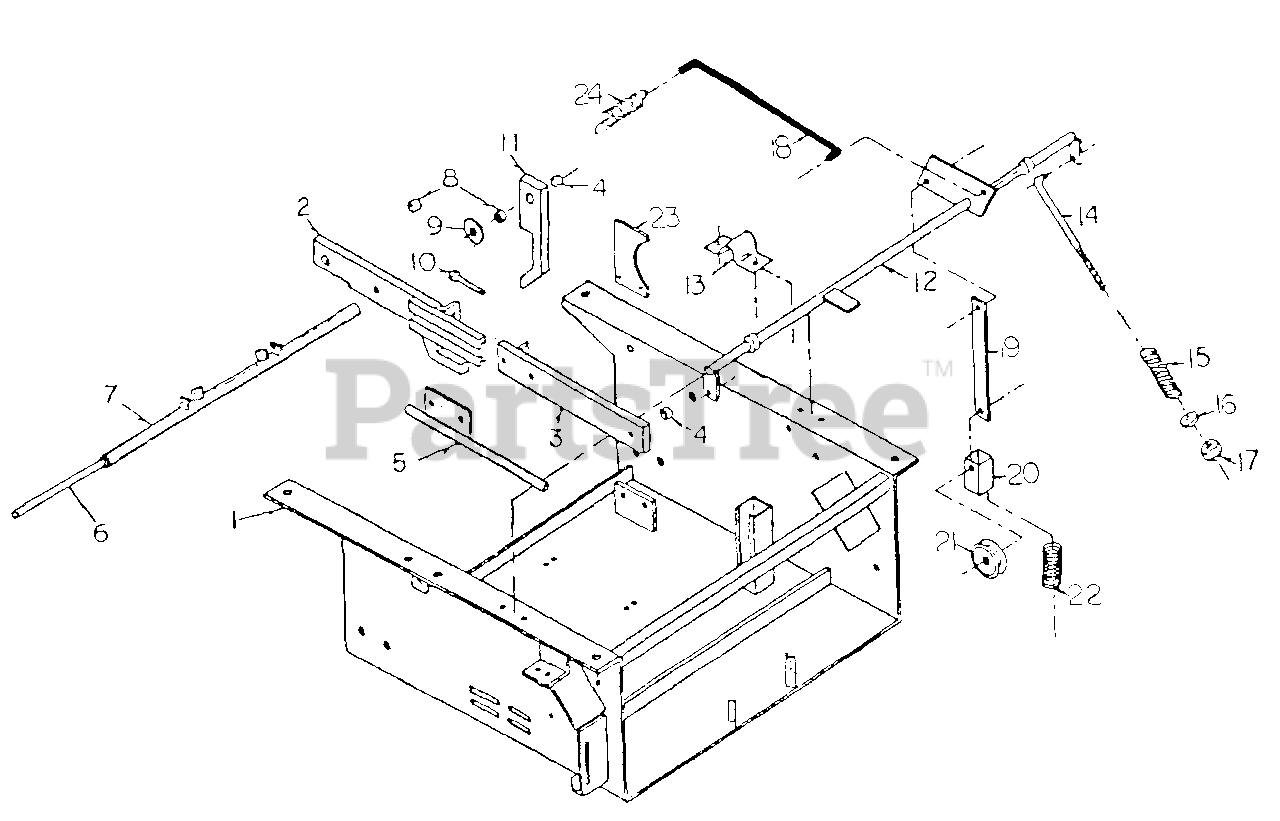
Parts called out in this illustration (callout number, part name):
1	Base
2	Deck Lift Arm, Front RH
3	Deck Lift Arm, Back RH
4	Bushing, Short
6	Cross Bar Pin
8	Bushing, Long
9	Body Mount Washer
10	Tap Bolt, 3/8-16 x 3", GR5
11	Forward Nose Down Lock
12	Brake Clutch Cross Rod
13	Bearing, Brake Cross Rod
15	Caliper Spring
16	Flatwasher, 1/4"
17	Elastic Stop Nut, 1/4-20
18	Brake Pedal Rod
19	Cross Rod to Idler Pulley Linkage
20	Spring Loaded Idler Mount
21	Idler Pulley
24	Brake Pedal Spring
